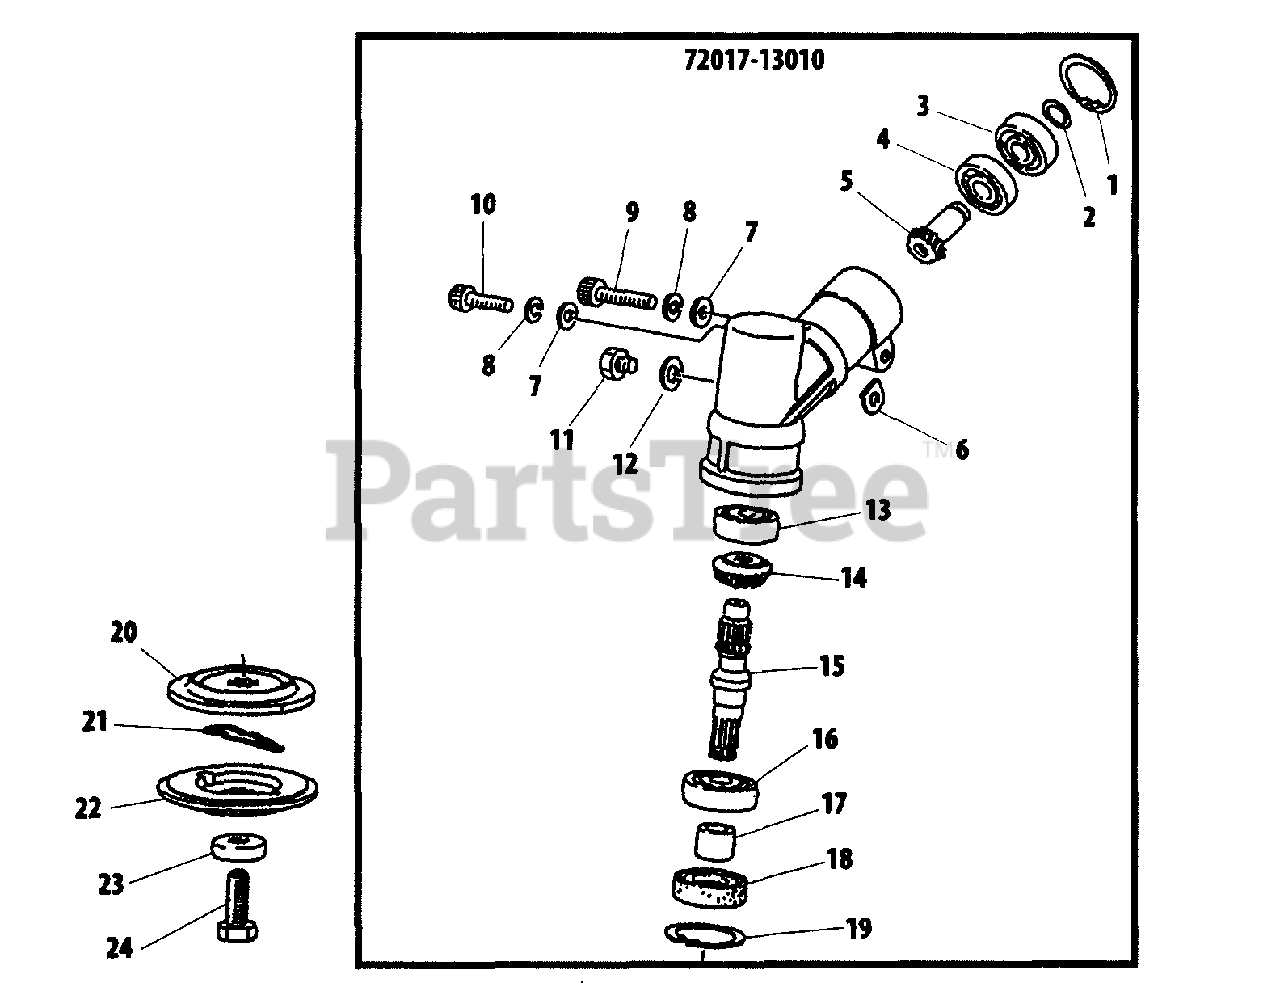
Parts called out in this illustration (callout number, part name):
1	RING, SNAP Ø28
2	RING, SNAP Ø12
3	BEARING, BALL 6001ZZ
4	BEARING, BALL 6001
5	GEAR, PINION
6	D-WASHER
7	WASHER 6.5×11.5×0.8
8	WASHER, SPRING 6
9	BOLT
10	BOLT
11	BOLT M6×10
12	WASHER
13	BEARING, BALL 6000DDU
14	GEAR, BEVEL
15	SHAFT, GEAR
16	BEARING, BALL 6202
17	COLLAR
18	SEAL, OIL
19	RING, SNAP Ø35
20	PLATE, ADAPTOR - UPPER
21	PIN, SLIDE
22	PLATE, ADAPTOR - LOWER
23	GUARD, BOLT
24	BOLT 10×30
72017-13010	GEAR CASE ASSY
